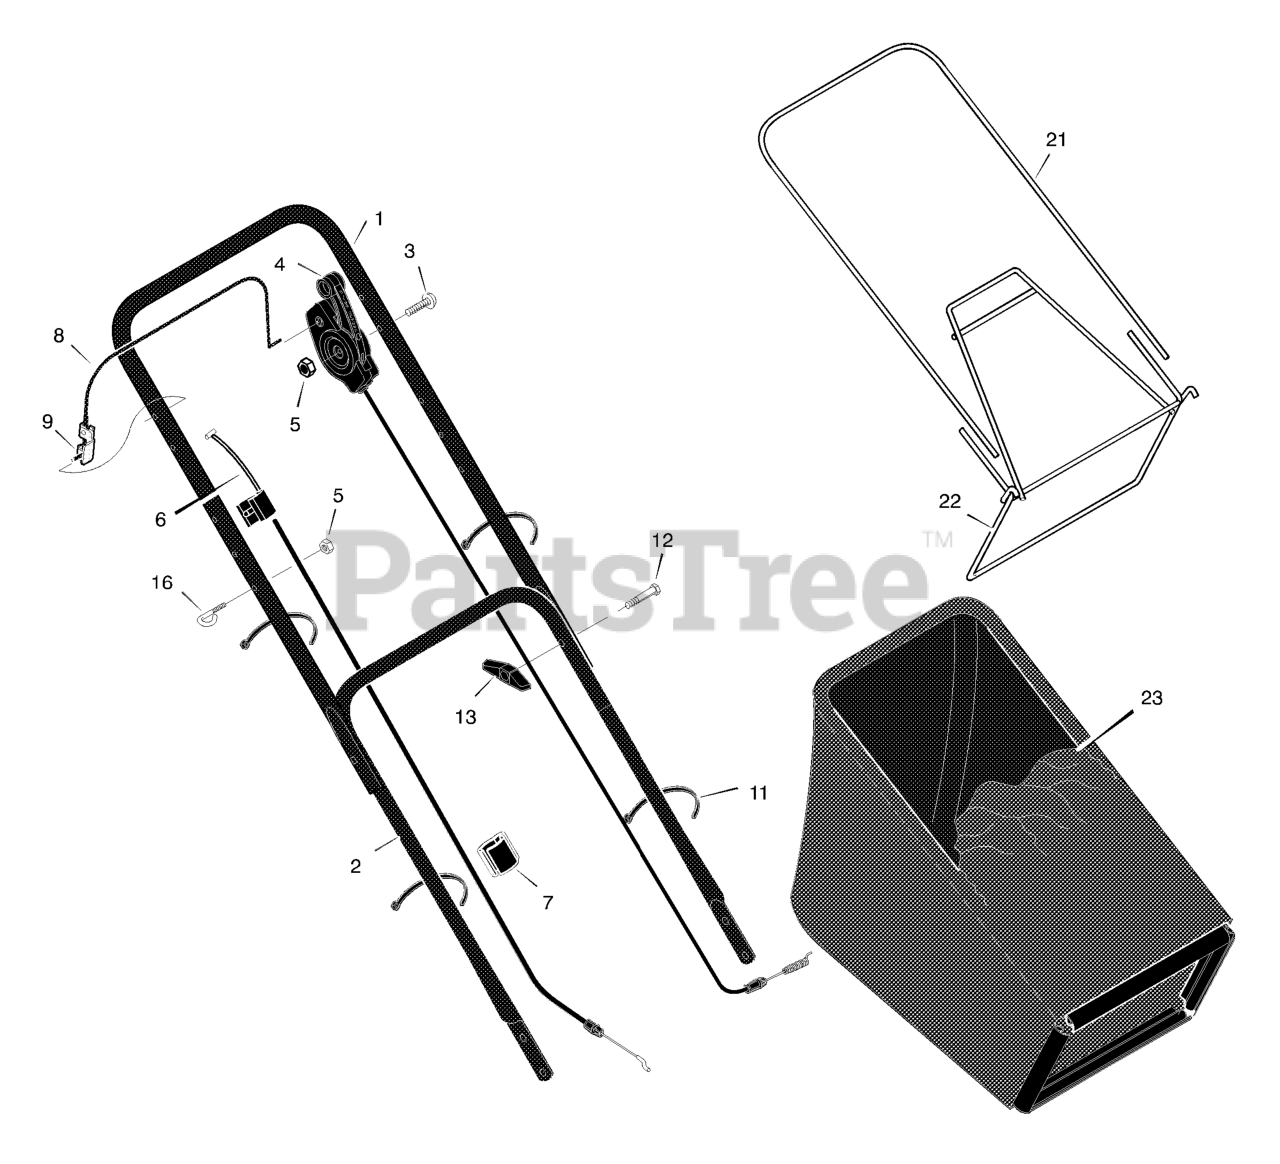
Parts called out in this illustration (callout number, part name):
1	Handle, Upper (Black)
2	Handle, Lower (Black)
4	Control, Drive
5	Locknut
6	Cable, Stop
7	Fastener, Single Cable
8	Lever, Stop
9	Bracket, Stop Lever
11	Fastener, Cable
13	Knob
16	Guide, Rope
21	Frame, Top
22	Frame Assembly
23	Bag, Cloth
